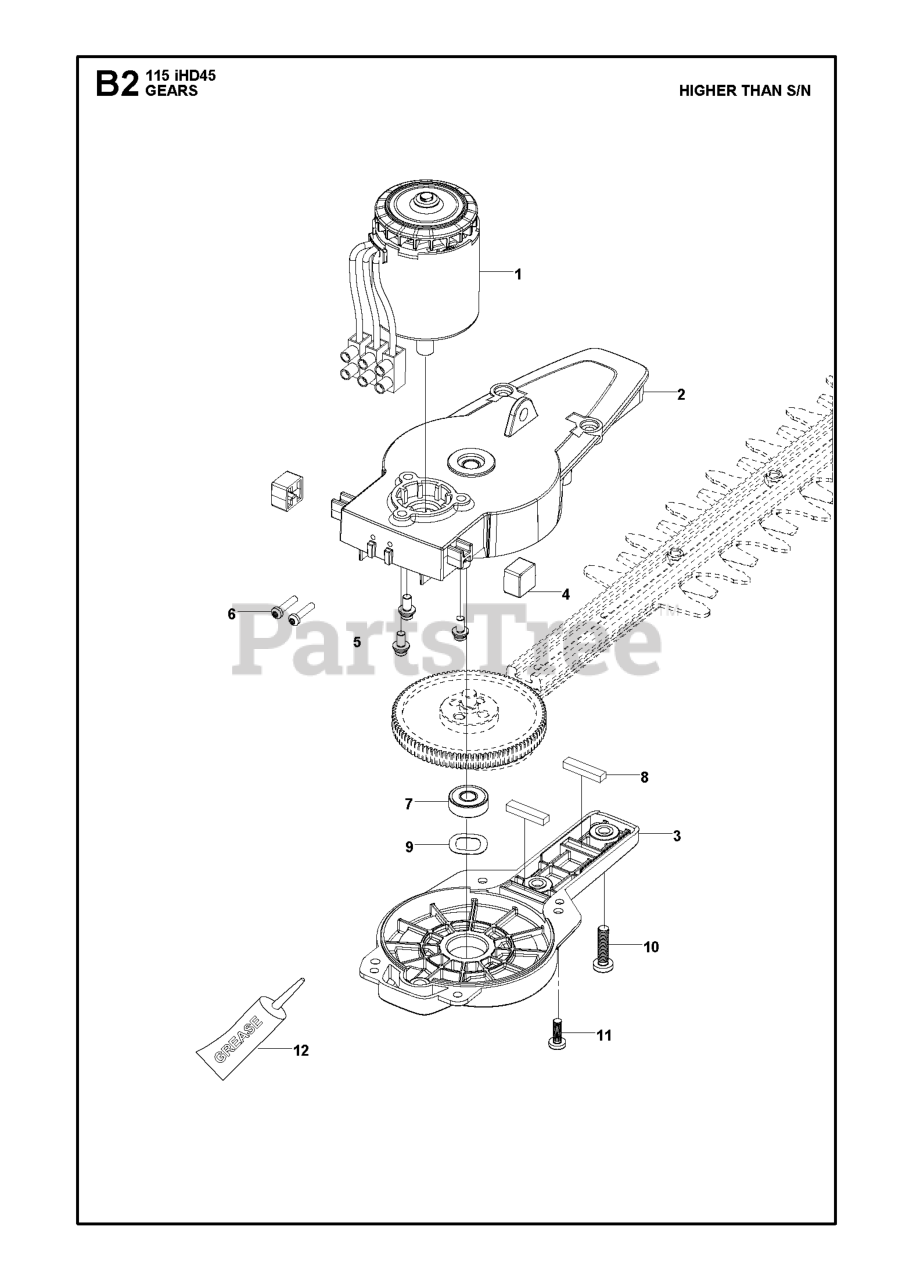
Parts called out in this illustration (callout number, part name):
3	COVER GEAR BOX
4	SHOCK ABSORBING
7	BALL BEARING
8	PAD DUSTPROOF
9	SPRING WASHER
10	SCREW M5X20
11	SCREW M4X12
12	GREASE 20G HEDGE TRIMMER GEAR
